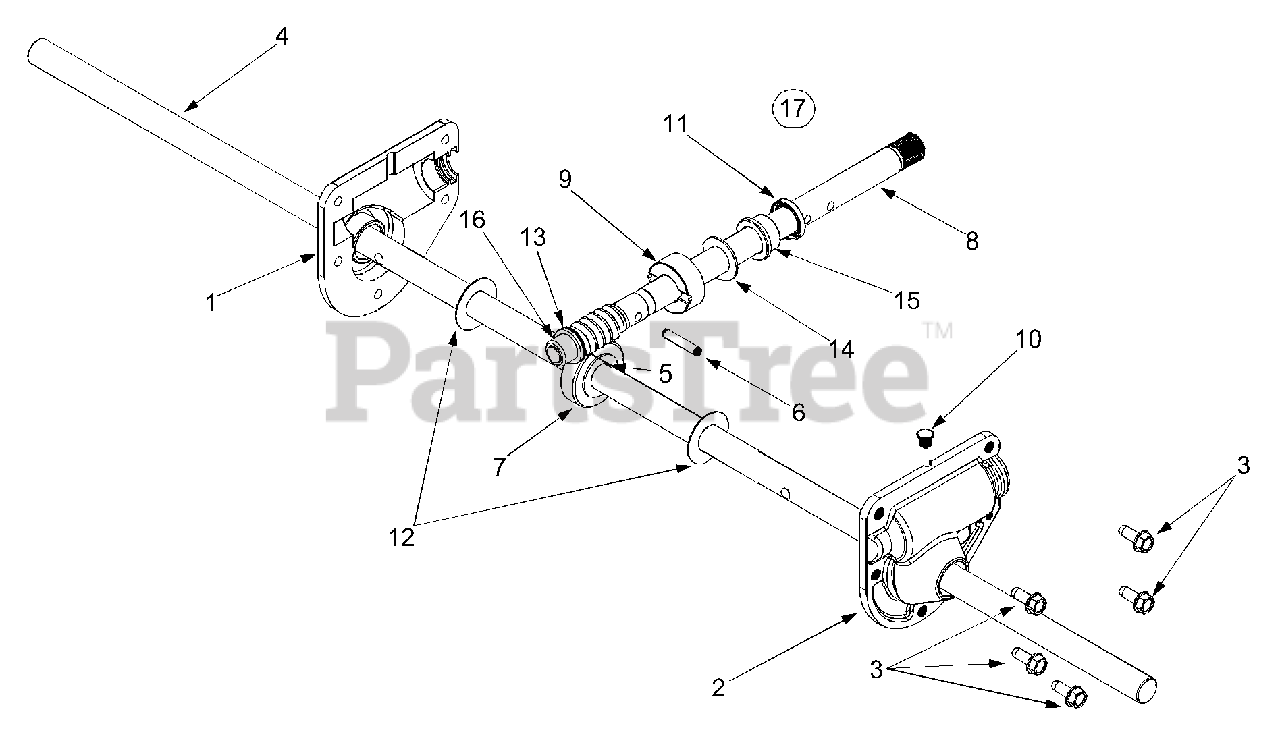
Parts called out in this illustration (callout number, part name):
1	Housing-R.H.
2	Housing-L.H.
3	Hex Screw 1/4-20 x.75
4	Spiral Axle 22"
4	Spiral Axle 24"
6	Spiral Pin
7	Worm Gear
8	Worm Shaft
9	Thrust Collar
10	Grease Plug
11	Grease Seal
12	Flat Washer.76 x 1.5 x.030
13	Flat Washer.508 x 1.0 x.020
14	Flat Washer.76 x 1.5 x.060
15	Flange Bearing.75 x 1.0 x.59
16	Flange Bearing.75 x 1.0 x.925
17	Ass'y. Complete 22"
17	Ass'y Complete 24"
